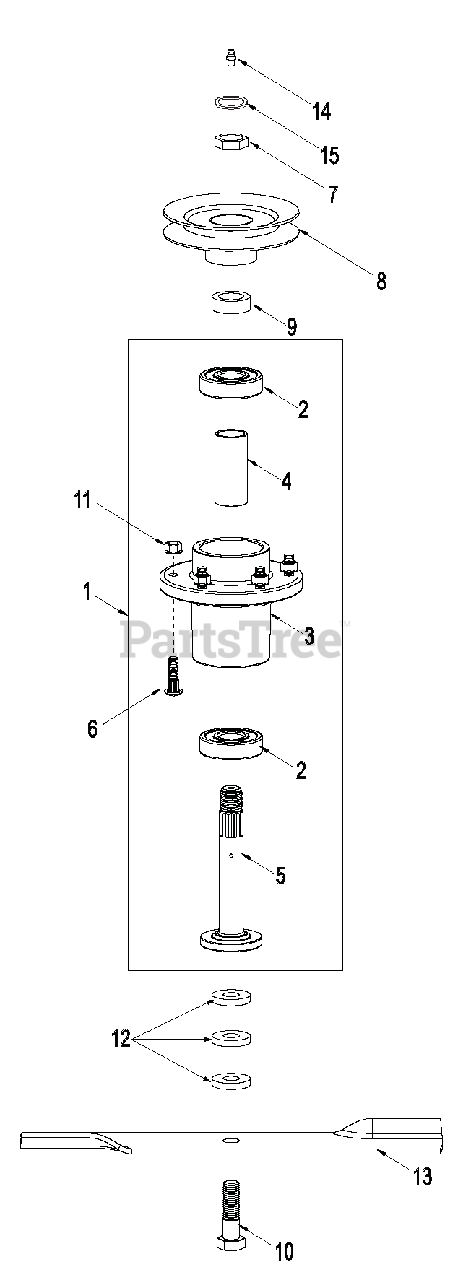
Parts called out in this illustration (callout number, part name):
1	ASSY, SPINDLE S/O
2	BEARING, 6305LLC
3	HOUSING, SPINDLE W/STUDS
4	SPACER, 1.250X1.000X2.780
5	SHAFT, SPINDLE 3/4-16
6	BOLT, 3/8-16X1.25RDHD RIBNKS/O
7	LOCKNUT, 3/4-16 CROWN PL
8	Pulley, Cutter Housing - See Mower Assembly Pages
9	SPACER, SPINDLE TOP-PULLEY
10	BOLT, 5/8-11 X 2.00 HEX 8 Y
11	NUT, 3/8-16 STD HEX GR5 Y
12	WASHER, .630X1.50X.250 FLAT Y
13	BLADE, 18.000 X .80 LIFT
13	BLADE, 16.500 X .80 LIFT
14	FTG, 1/4-28 STRGT GREASE ZERK
15	RING RETAINER S/O
